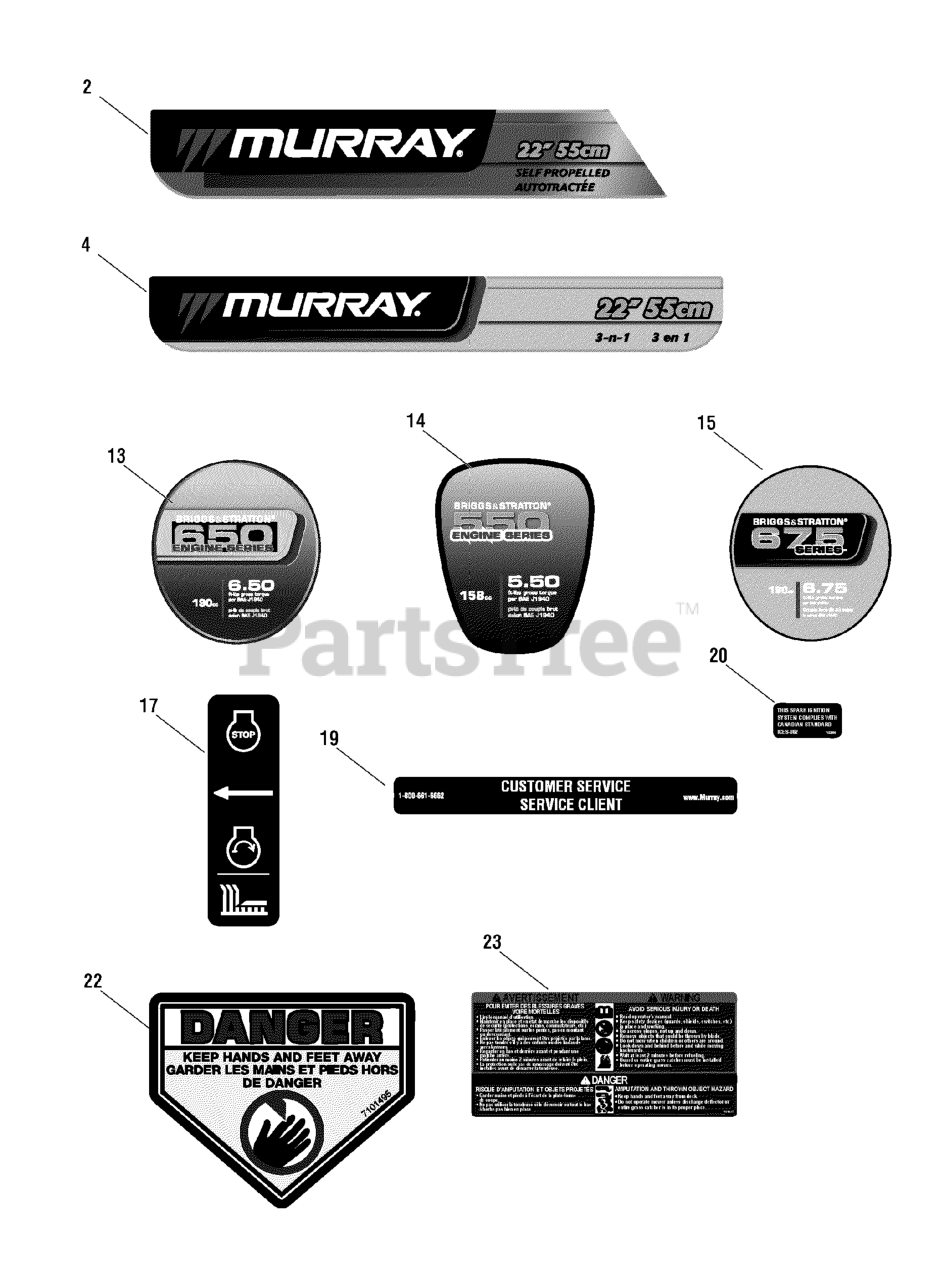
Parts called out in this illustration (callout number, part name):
2	DECAL, Murray Logo, Deck, SS, FC
4	DECAL, Murray Logo, Deck, Push, FC
13	DECAL, Engine, TP, 650, Murray, FC
14	DECAL, Engine, TP, 550 FC
15	DECAL, Engine, TP, 675 FC
17	DECAL, OPC Bail International Symbol
19	DECAL, Customer Service, Murray
20	DECAL, ICES, Canadian Spark Compliance
22	DECAL, CPSC, FR/ENG
23	DECAL, WB Safety, French/English
